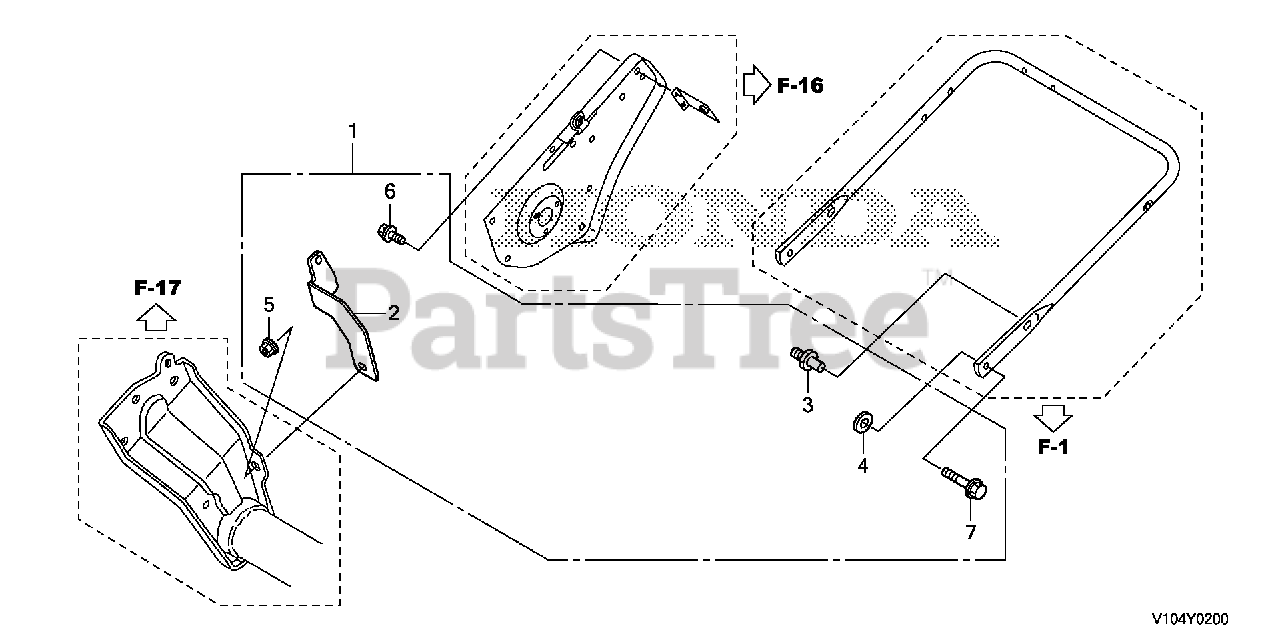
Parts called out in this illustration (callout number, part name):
1	MOUNT KIT, HANDLE
2	STAY, ENGINE BED
3	BOLT, SPECIAL (8MM)
4	WASHER (8.5MM)
5	NUT, FLANGE (6MM)
6	BOLT, FLANGE (6X14)
7	BOLT, FLANGE (8X25)
